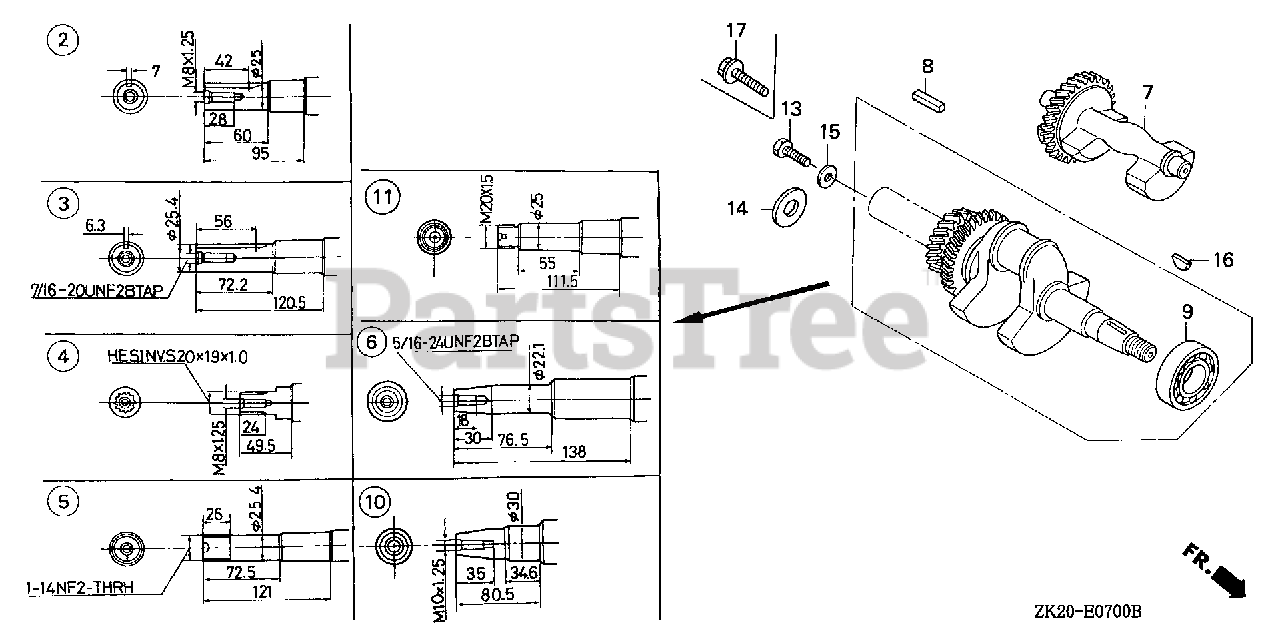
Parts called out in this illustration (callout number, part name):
6	CRANKSHAFT
7	WEIGHT, BALANCER
9	BEARING, RADIAL BALL (6206)
16	KEY, SPECIAL WOODRUFF (25X18)
